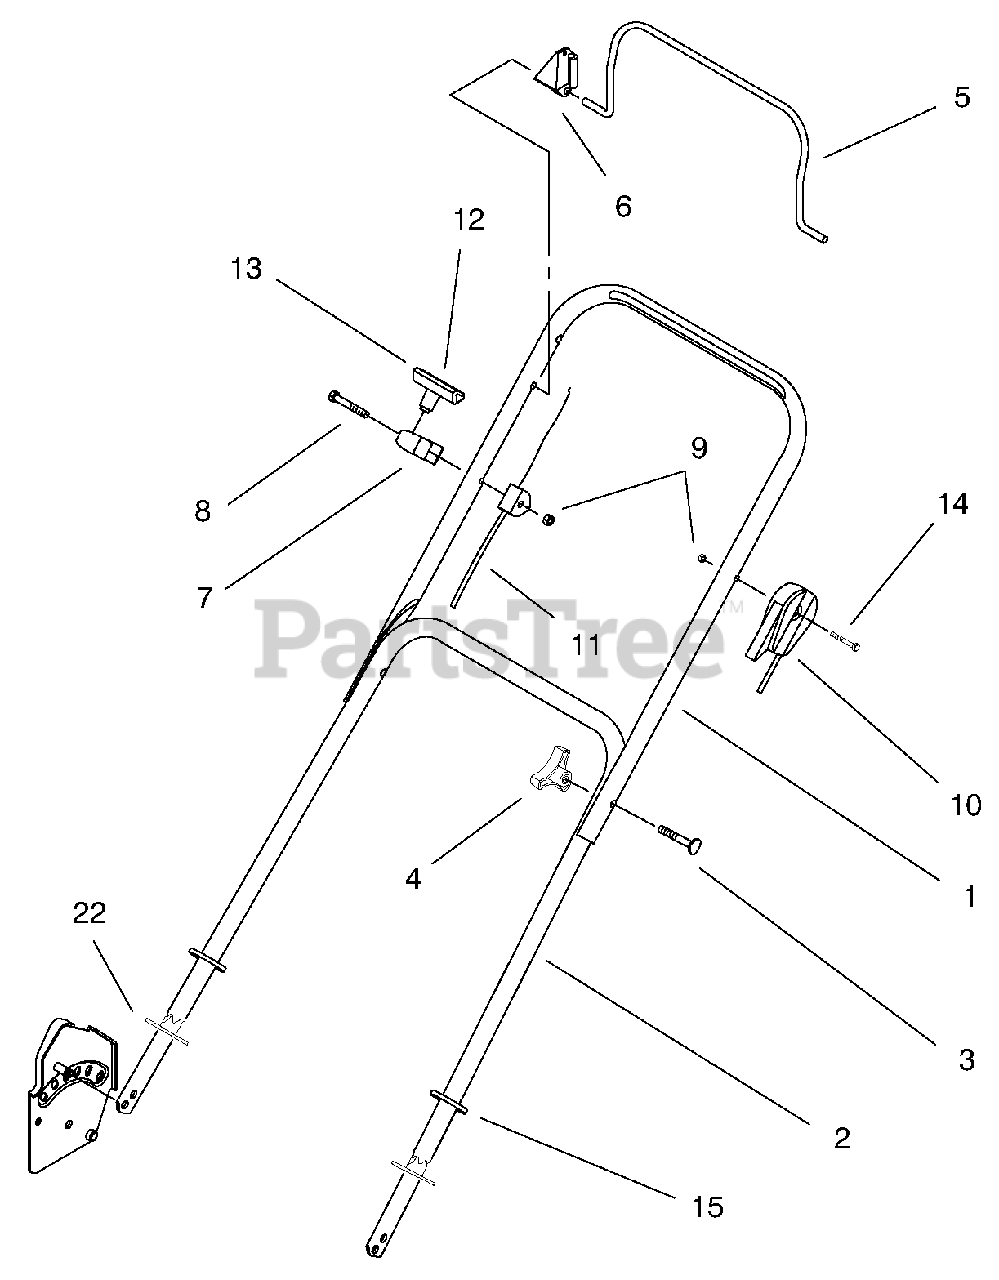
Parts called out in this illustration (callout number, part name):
1	Handle Section-Upper
2	Handle Section-Lower
3	Screw-Handle
4	Knob
5	Bail-Flywheel Brake
6	Stop-Pivot
7	Guide-Rope
9	Nut-Lock
10	Cable-Throttle
11	Cable-Flywheel Brake
12	Clip-Rope
13	Handle-Starter
14	Screw-HH
15	Tie-Cable
22	Handle-Guard
